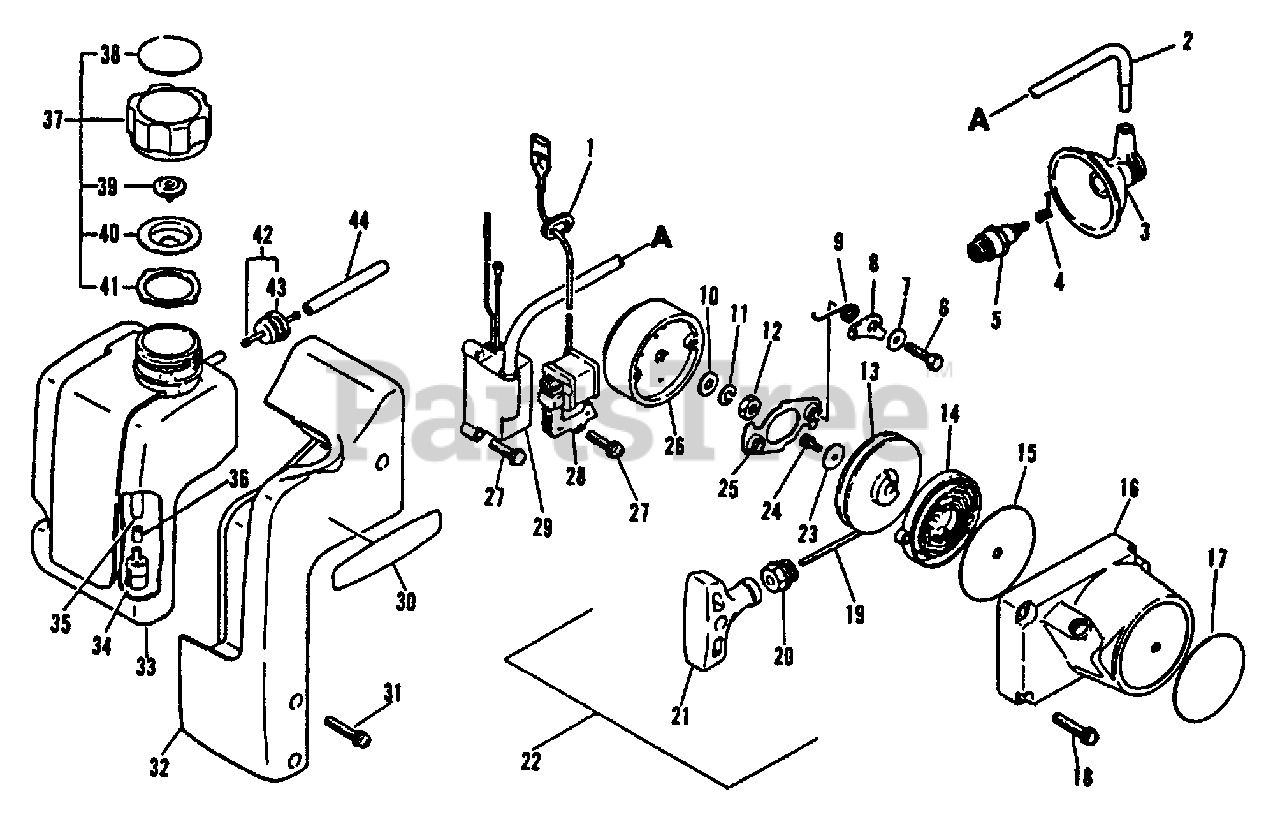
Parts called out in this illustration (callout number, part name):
3	CAP, SPARK PLUG
4	TERMINAL, SPARK PLUG CAP
5	SPARK PLUG -- BPM-7A
6	BOLT - 5X20
7	WASHER - 5
8	PAWL, STARTER
9	SPRING, RETURN
10	WASHER - 8
11	LOCKWASHER - 8
13	REEL, ROPE
14	SPRING, REWIND
15	PLATE, STARTER
16	CASE, STARTER
17	LABEL - ECHO
18	SCREW - 5X25
19	ROPE, STARTER - 3X850
20	GUIDE, ROPE
21	GRIP, STARTER
22	STARTER ASSY
24	SCREW - 4X10
25	HOLDER, PAWL
26	FLYWHEEL
27	SCREW - 4X20
28	COIL, EXCITER
29	COIL, IGNITION
30	LABEL - ECHO
31	SCREW - 4X25
32	BRACKET, FUEL TANK
33	TANK, FUEL
34	FILTER, FUEL
35	PIPE - 3X7X135 -- BLACK
37	CAP ASSY
38	LABEL - FUEL MIX
40	HOLDER, VENT
41	GASKET, CAP
42	GROMMET KIT
44	PIPE, FUEL - 3X7X65
